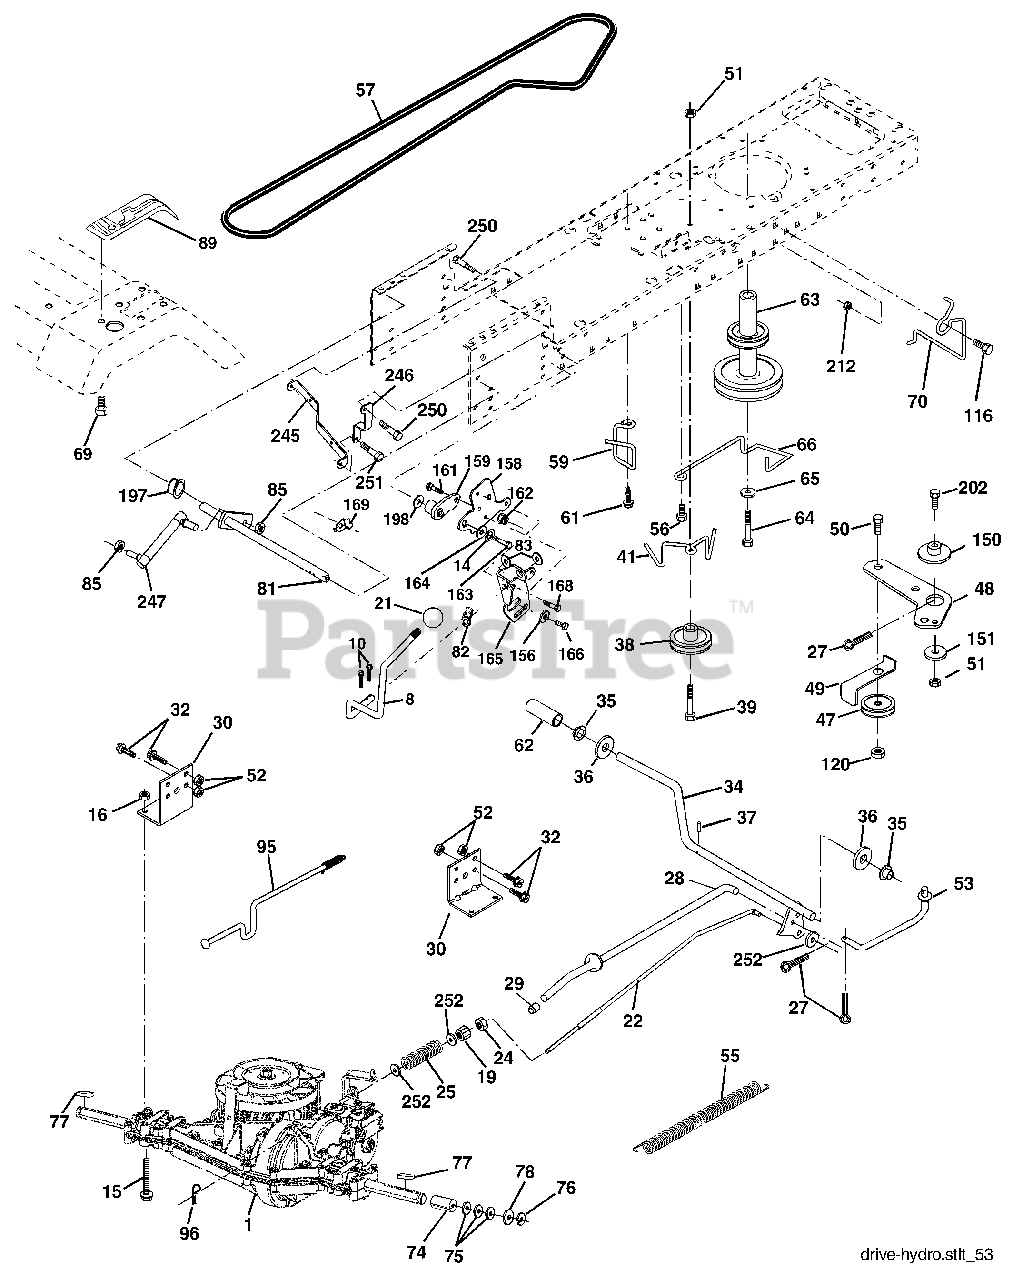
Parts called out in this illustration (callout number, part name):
8	Rod Shift Fender Adjust
10	Pin Cotter 1/8 x 1 CAD
14	Washer Lock Hvy Helical
15	Bolt Hex FLGHD 5/16-18 Gr.5
16	Nut Lock Hex W/Ins. 5/16-18 Unc
19	Nut Lock Hex W/Wsh 3/8-16 Unc
21	Knob 1/2-13
22	Rod, Brake
24	Nut, Hex Jam 3/8-16 Unc
25	Spring, Brake Rod
27	Pin Cotter 1/8 x 3/4 CAD.
28	Rod, Parking Brake
29	Cap, Parking Brake
30	Bracket, Transaxle
32	Bolt Hex Hd 5/16-18 Unc x 3/4
34	Shaft, Foot Pedal
35	Bearing, Nylon
36	Washer
37	Pin, Roll
38	Pulley, Composite
39	Bolt Fin Hex 3/8-16 x 3
41	Keeper, Belt Idler
47	Pulley, Idler, V-Groove
48	Bellcrank, Clutch
49	Retainer, Belt
50	Bolt Carr Sh 3/8-16 x 1-1/2 Gr 5
51	Nut Crownlock 3/8-16 Unc
52	Nut, Crownlock 5/16-18 Unc
53	Link, Clutch
55	Spring, Return, Clutch
56	Screw 3/8-16 x 1-1/4
57	V-Belt
59	Keeper, Center Span
61	Screw 3/8-16 x .875
62	Cover, Pedal
63	Pulley, Engine
64	Bolt Hex 7/16-20 x 4 Gr. 5
66	Keeper Belt Engine Hydro
69	Screw Hex Wsh Hi-Lo 1/4-1/2 Unc
70	Keeper Belt Engine
74	Spacer
75	Washer 25/32 x 1-1/4 x 16 Ga.
77	Key, Square
78	Washer 25/32 x 1-5/8 x 16 Ga.
81	Shaft Asm Cross Tapered
82	Spring Torsion
83	Washer 17/32 x 3/4 x 16 Ga.
85	Nut Lock Center 1/4-28 FNTHD
89	Console, Shift
95	Disconnect Asm Rod Bypas LTH
96	Retainer Spring 1" Zinc/Cad
116	Bolt Rdhd Sqneck 3/8-16 x 1
120	Nut Lock Flg 3/8-16
150	Spacer Retainer
151	Washer 13/32 x 2 x 10 Ga.
156	Washer Srrted 5/16 ID x 1.125
158	Bracket Shift Mount
159	Hub Shift
161	Bolt Rdhd Sqnk 1/4-20 x 3/4 Gr 5
162	Nut Crownlock 1/4-20 Unc
163	Bolt Hex Fin 1/4-20 Unc x 1 Gr 5
164	Washer 5/8 x .281 x 10 Ga
165	Bracket Pivot Lever
166	Screw 5/16-18 x 5/8
168	Bolt Shoulder 5/16-18 x .561
169	Plate Fastening
197	Nyliner Snap-In 5/8" ID
198	Washer Nyl 7/8 ID x .105" Hyd
202	Bolt Carr Sh 3/8-16 x 1-3/4 Gr.5
212	Nut Hex Flange Lock
245	Strap Torque Lh LTH2000
246	Strap Torque Rh LTH2000
247	Link Shift Transaxle LTH2000
250	Screw 3/8-16 x 3/4
251	Screw 5/16-18 x 1
252	Washer 13/32 x 1 x 16 Ga.
